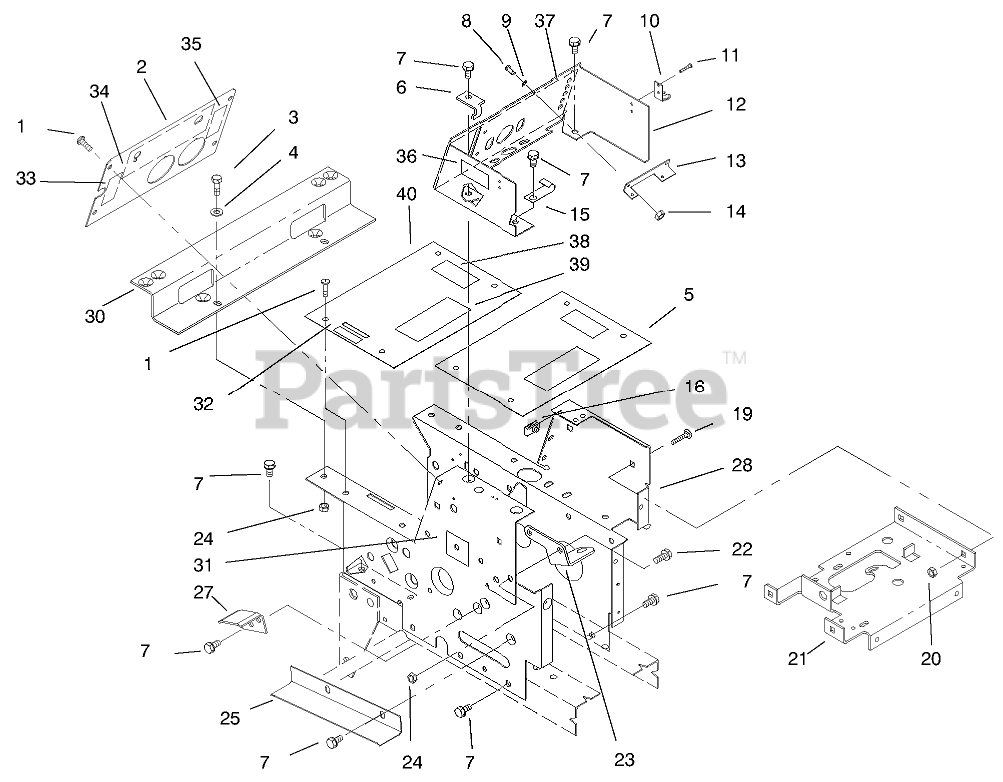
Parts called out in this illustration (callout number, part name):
1	SCREW-PPH
2	PLATE-HOODSTAND (BLACK)
3	SCREW-HH
4	WASHER-PLAIN
5	Plate-Top Hoodstand
6	STOP-PTO
7	Bolt
8	SCREW-PAN
9	Washer-Lock
10	KEEPER-LATCH
11	RIVET-POP
12	Console
13	BRACKET
14	Nut
15	J-CLIP
19	BOLT CARR. 5/16X1/2 BK
20	Nut
21	Bracket-Battery Support
22	SCREW-HH
23	BRKT-LR CNTROL (BLACK)
24	NUT-LOCK, NI
28	Hoodstand
30	Bracket-Fender
31	DECAL - MODEL 416-H
33	DECAL PTO CLUTCH
34	DECAL-BACK PLATE
35	DECAL-CHOKE
36	DECAL ELECT SYSTEM
37	DECAL-DASH
38	DECAL-PARKING BRAKE
39	DECAL-DANGER
